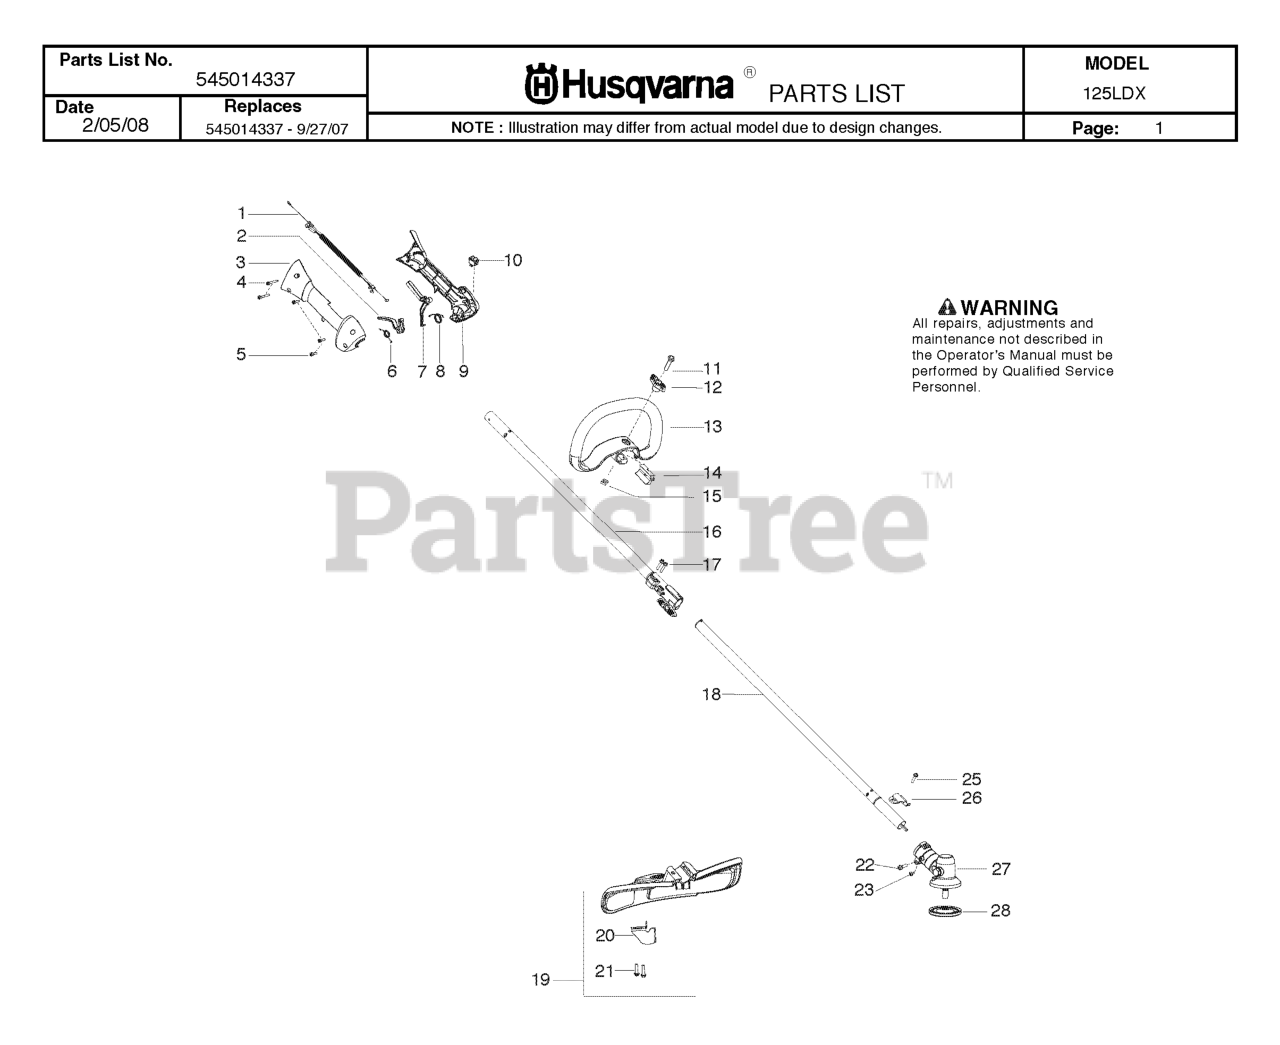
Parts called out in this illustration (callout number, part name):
1	ASSY-CABLE WIRE HARNESS
2	TRIGGER THROTTLE
3	HOUSING-THROTTLE RH
5	SCREW M4 X 1.75 PT 16MM
6	SPRING TRIGGER
7	THROTTLE LOCKOUT
8	SPRING LOCKOUT
9	HSG THROTTLE LH
10	KIT SWITCH
11	SCREW M6X50
13	ASSY LOOP HANDLE
14	SPACER PLASTIC
16	DRIVE SHAFT
18	KIT DRIVESHAFT LOWER LDX
19	KIT COBI SHIELD
20	Limiter - Line
22	SCREW - CARB. ADAPTOR
24	T25 10MM LH TRIMMER HEAD
25	SCREW 1/4-20 X 7/8 (TAP
26	BRACKET SHIELD STRAIGHT SHAFT
27	ASSY GEARBOX
28	DRIVE DISC
